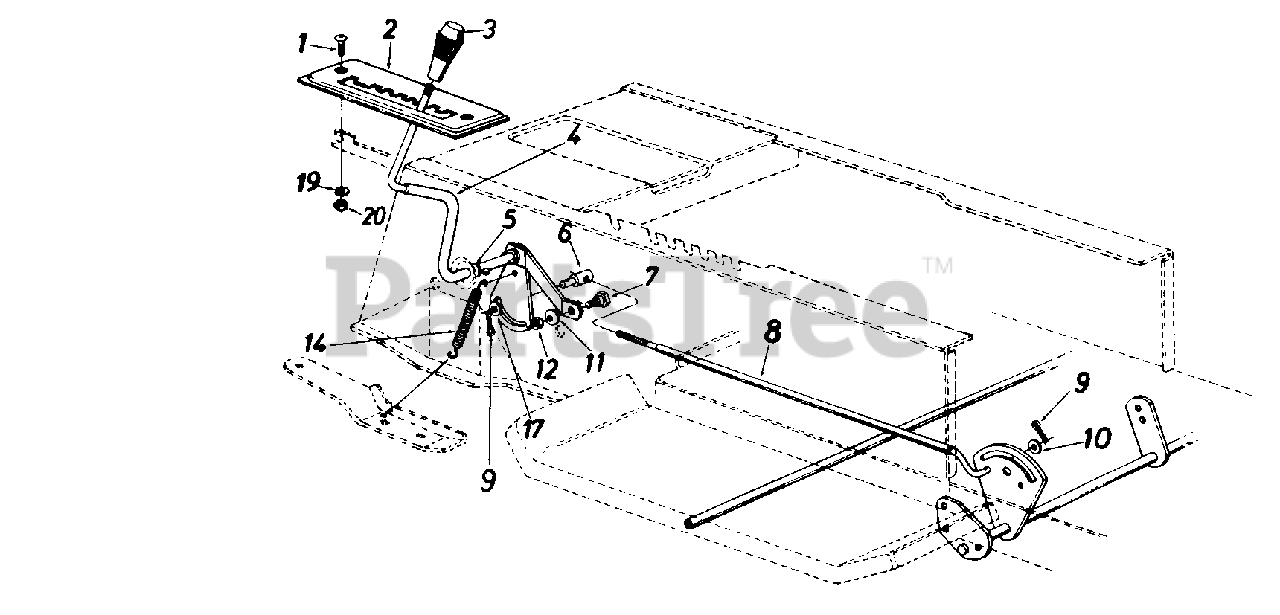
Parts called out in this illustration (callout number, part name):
1	Truss Mach. Scr. 1/4-20 x .75" Lg.
4	Speed Selector Cam Ass'y.
5	Flat Washer .53" I.D. x .93"
6	Ferrule 3/8-24 x .37" Dia.
7	Shoulder Bolt
8	Speed Control Link
9	Cotter Pin 3/32" Dia. x 1.0"
10	Fl-Wash. .469" I.D. x .88"
11	L-Wash. 5/16" I.D.
12	Hex Nut 5/16-18 Thd.
14	Spring .38" O.D. x 3.18" Lg.
17	Fl-Wash. .385" I.D. x .62"
19	L-Wash. 1/4" I.D.
20	Hex Nut 1/4-20 Thd.
